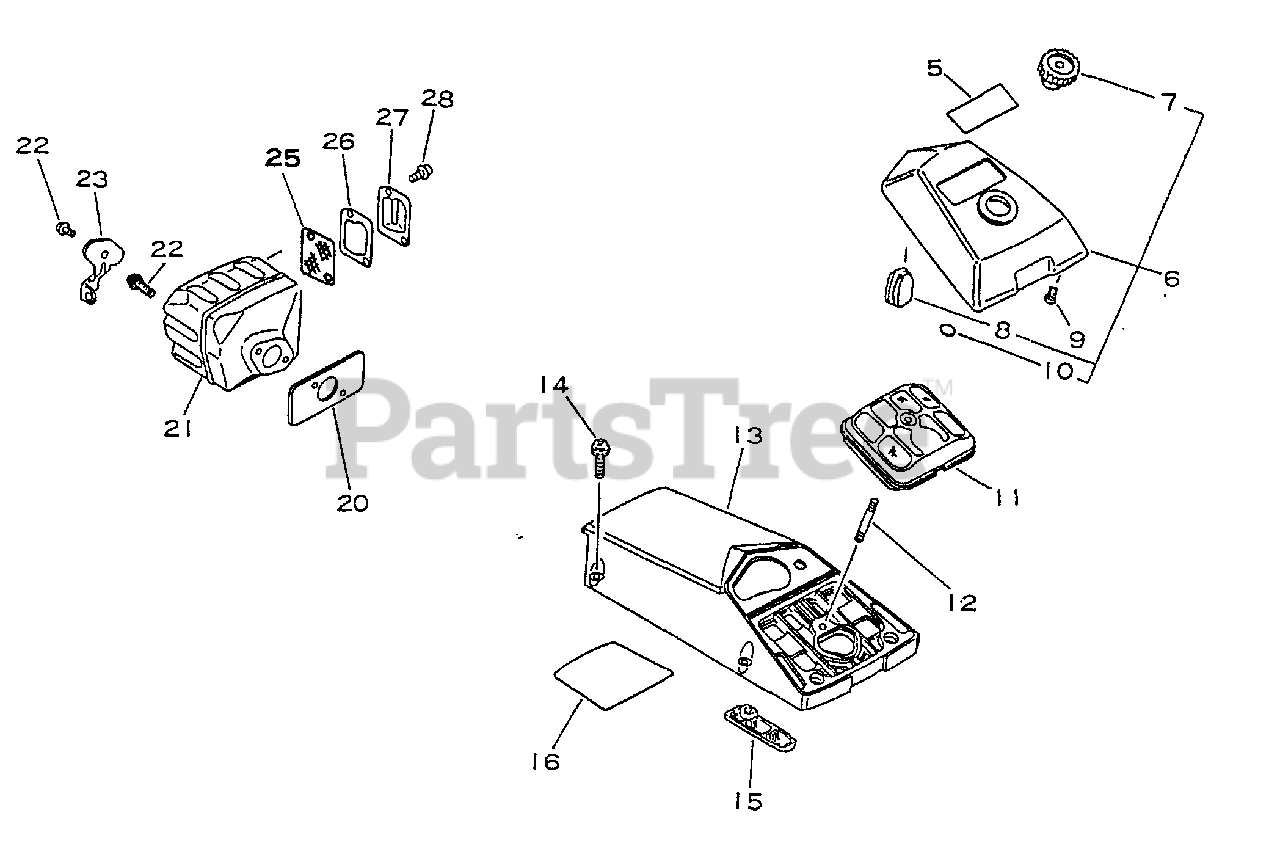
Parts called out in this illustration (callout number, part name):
5	LABEL - MODEL
6	COVER, AIR FILTER
7	WINGNUT
10	O-RING P-11
11	FILTER, AIR
13	COVER, CYLINDER
14	SCREW 5×20
15	FILTER
21	MUFFLER
22	BOLT M5×10
23	BRACKET, MUFFLER
25	SCREEN, SPARK ARRESTER
26	GASKET, MUFFLER
27	COVER, MUFFLER
28	SCREW 4×8
